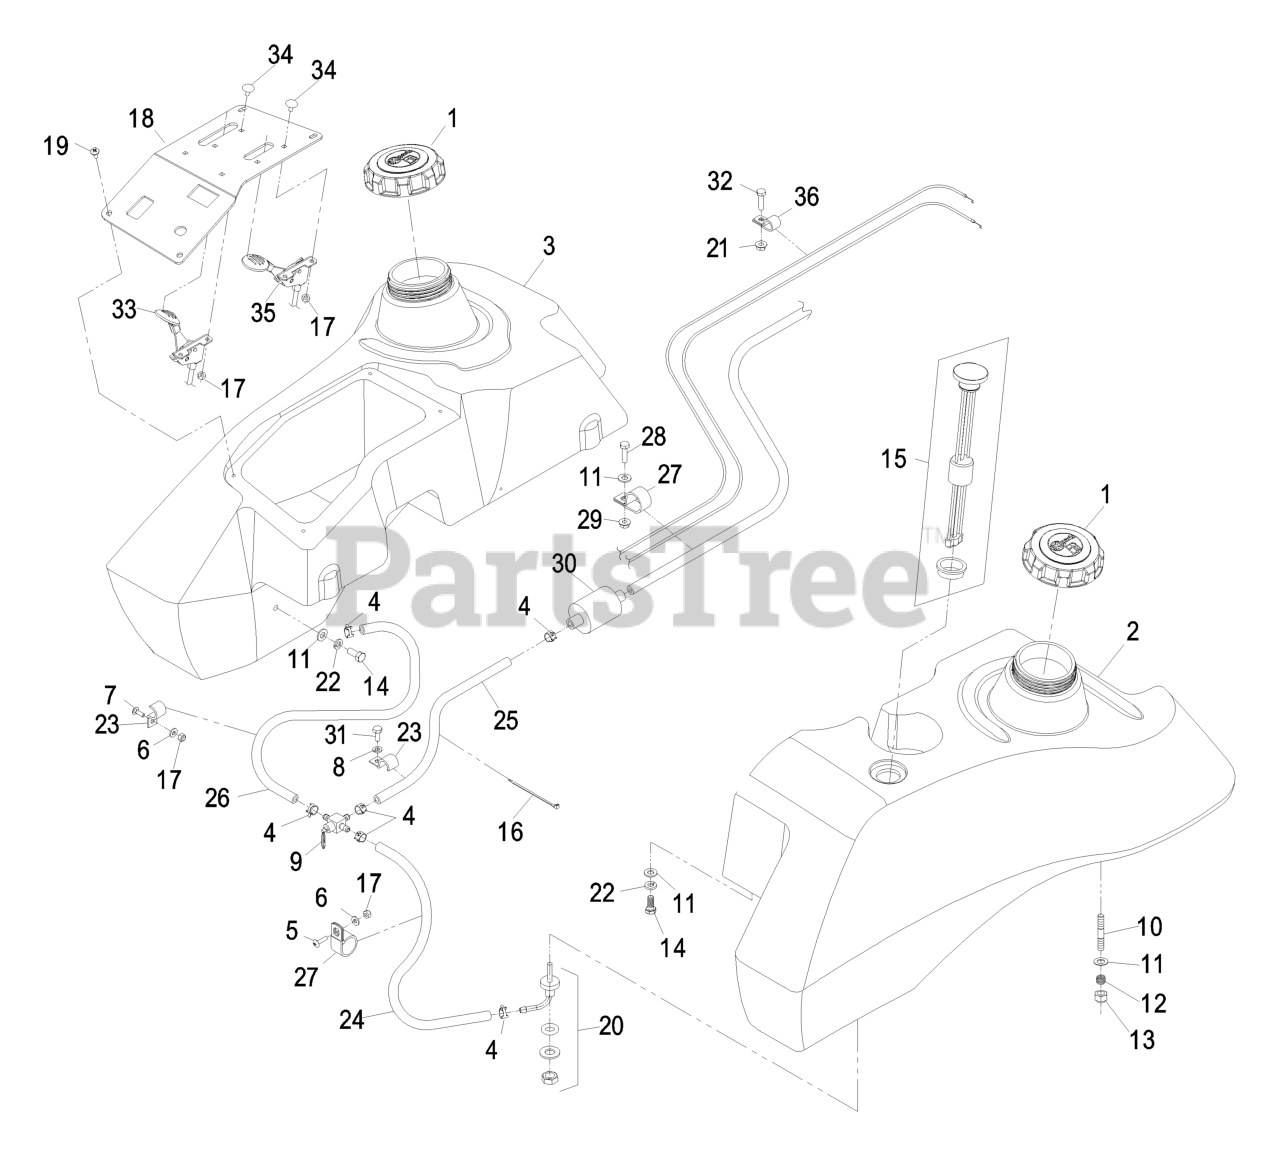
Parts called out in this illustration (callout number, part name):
1	CAP-FUEL, GAS
2	KIT,FUEL TANK LH LZXS
3	KIT,FUEL TANK RH LZXS
5	SCREW-HEAD, TRUSS
6	WASHER-FLAT
7	BOLT-CARR
8	WASHER-LOCK
9	VALVE-FUEL
10	STUD
11	WASHER-PLAIN
12	SPRING-TANK, FUEL
13	NUT-LOCK, NI
14	SCREW-HH
15	KIT, CT FUEL GAGE REPL.
16	TIE-PLASTIC
17	NUT-LOCK, NI
18	PANEL,CONTROL W/DECALS
19	SCREW-PPH
20	FITTING-FUEL, BULKHEAD
22	WASHER-LOCK
23	CLIP-HALF, LOOM
24	HOSE-FUEL
26	HOSE-FUEL
27	CLIP-LOOM
28	SCREW-HH
30	Briggs & Stratton P/N 695327 Fuel Filter
31	SCREW-HH
32	SCREW-HH
33	CONTROL,CHOKE
34	BOLT-CARR
35	CONTROL-THROTTLE
36	CLIP-LOOM
